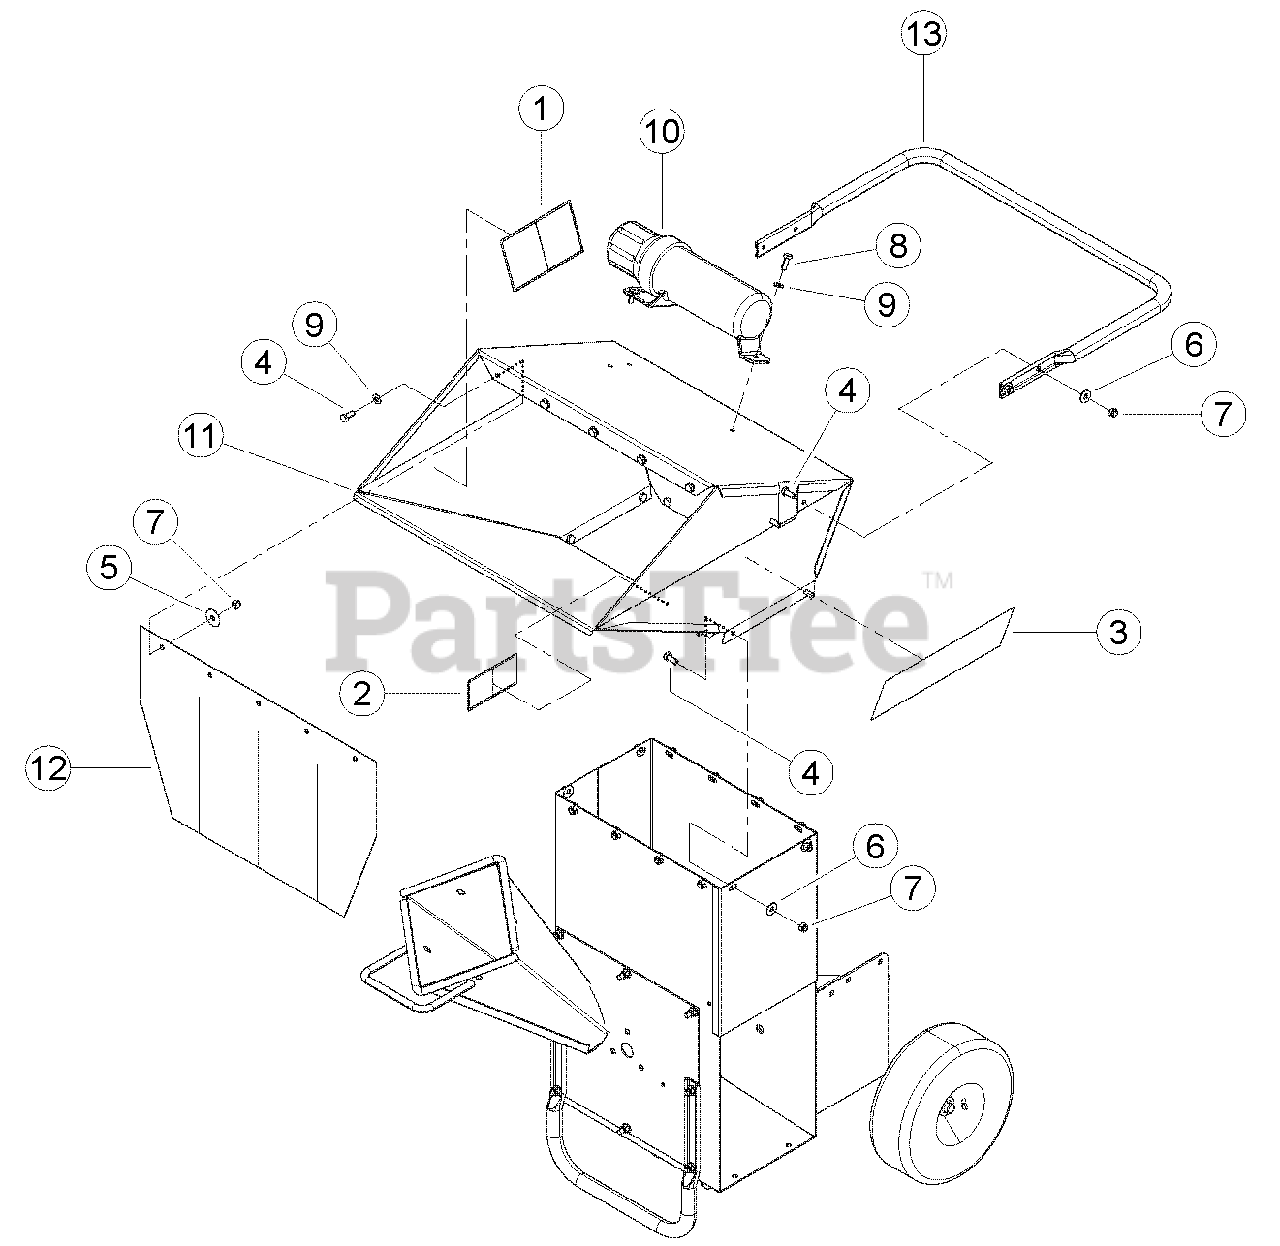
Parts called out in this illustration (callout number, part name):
1	DECAL, BLADE DANGER ISO
2	DECAL, SHREDDER SIZE ISO
3	DECAL, ECHO BEARCAT 12.00 X 4.00
4	BOLT, 5/16 X 3/4 HEX HD GR5 ZP
5	WASHER, 5/16 FENDER ZP
6	WASHER, 5/16 FLAT ZP
7	NUT, 5/16 NE NYLOCK ZP
8	BOLT, 5/16 X 7/8 HHCS GR5 NC ZP
9	WASHER, 5/16 SAE FLAT ZP
10	CONTAINER, MANUAL
11	WELDMENT, WIDE HOPPER
11	WELDMENT, NARROW HOPPER (SC3206)
12	BELTING, HOPPER
13	HANDLE, HOPPER
